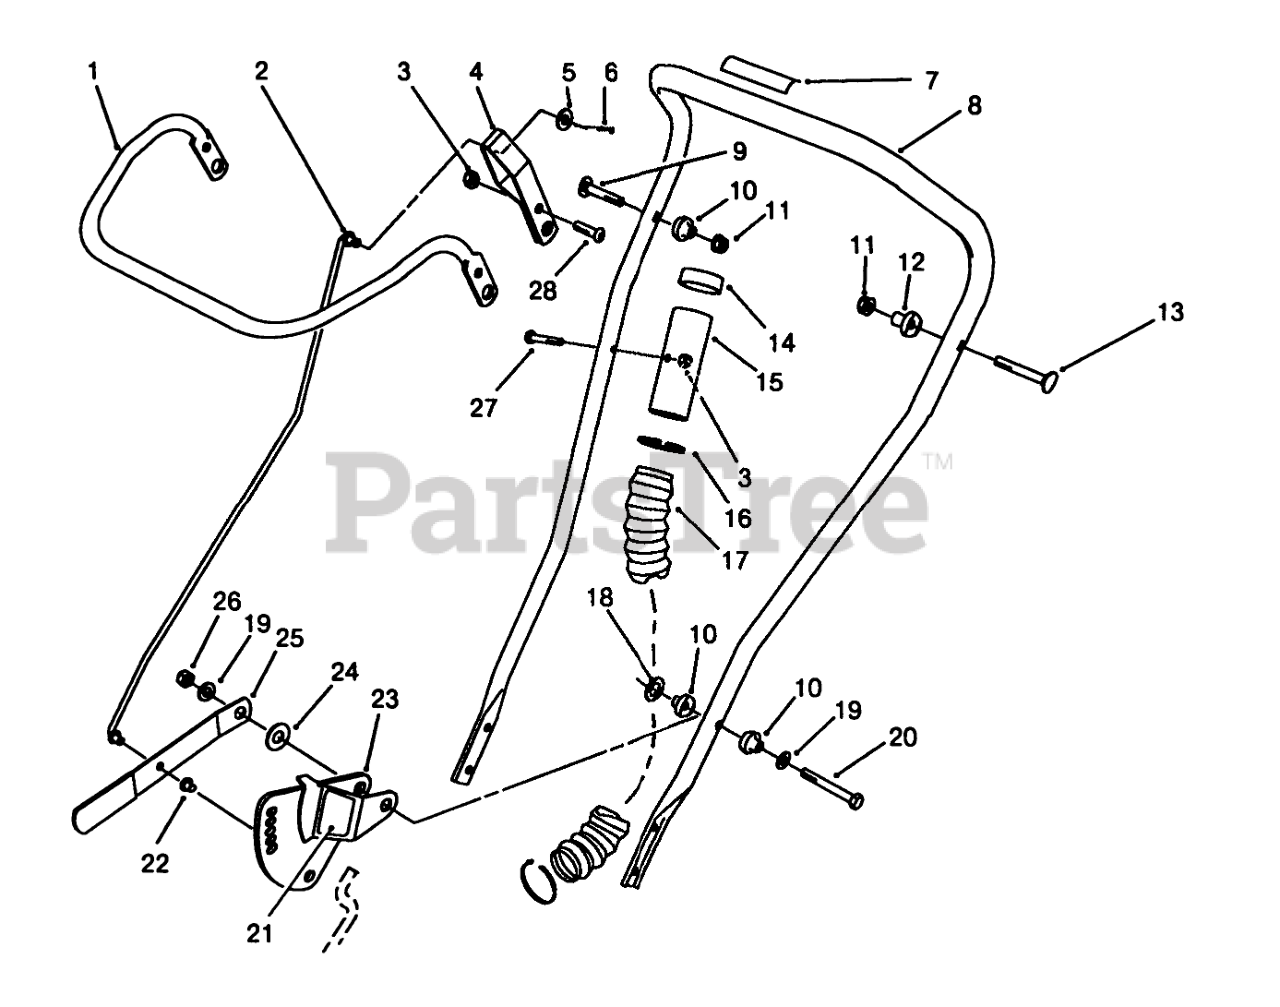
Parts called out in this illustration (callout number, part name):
1	Bar-Control
2	UPPER CONTROL ROD
3	NUT-LOCK, NI
4	CONTROL BAR BRKT.
5	WASHER-FLAT
6	PIN-COTTER
7	DECAL
8	UPPER HANDLE
9	SCREW-HANDLE
10	PIVOT SPACER
11	NUT-LOCK, NI
12	SPACER-SUPPORT
13	5/16-18 X 2 HNDLE SCREW
14	BLACK CAPLUG
15	AIR CLNR HOSE TIP
16	TIE-CABLE
17	AIR CLEANER HOSE
18	WASHER
19	WASHER-PLAIN
20	SCREW-HH
21	DECAL
22	PUSHNUT
23	ADJ.PLATE WA
24	WASHER
25	ADJ.HANDLE
26	NUT-LOCK, NI
27	SCREW-HH
28	SCREW-HSBH
